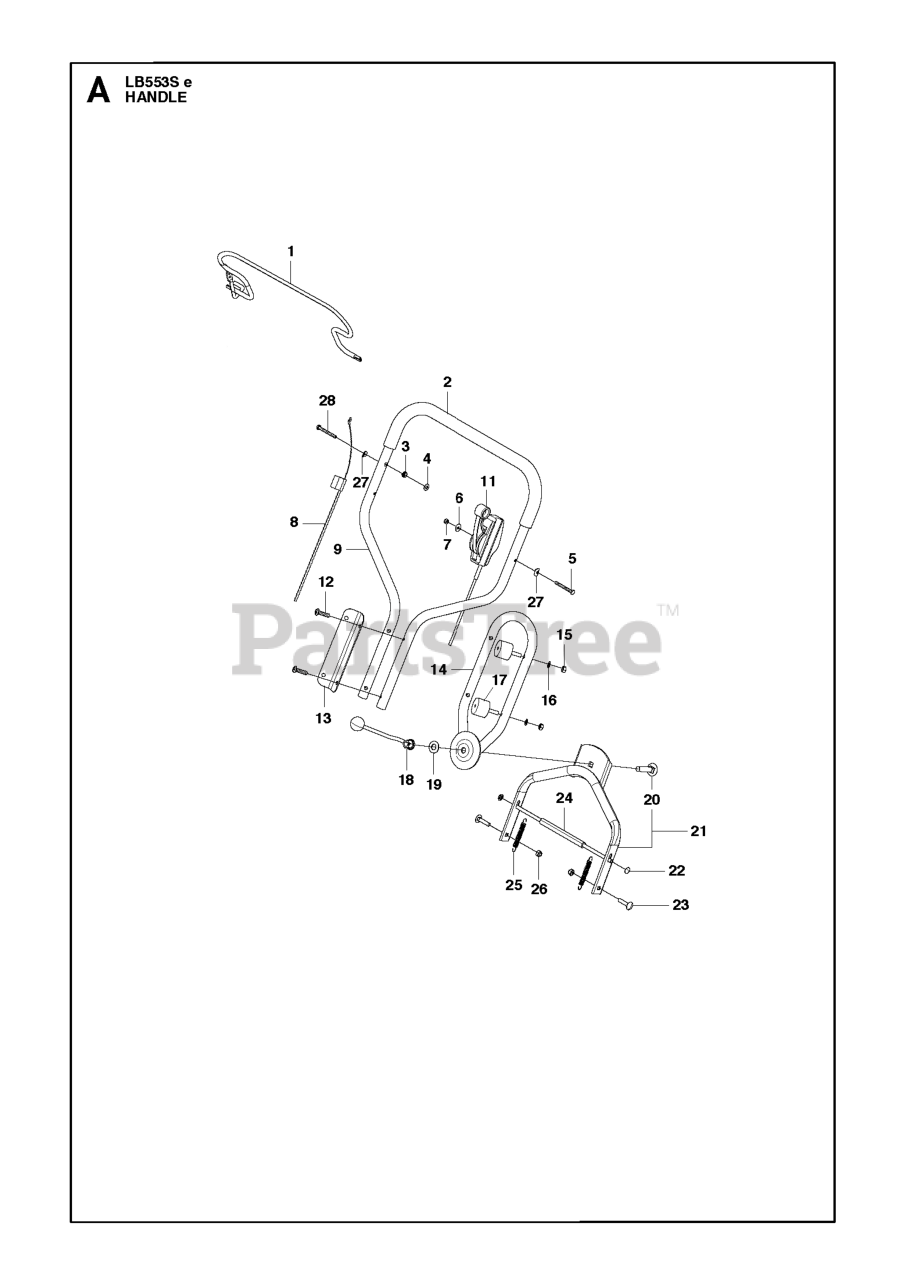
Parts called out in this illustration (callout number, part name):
5	SCREW M6X55
7	NUT FLANGE - M6
15	NUT
22	WASHER STARLOCK WITH CAP
23	RETAINING RING SGA 10
26	LOCKNUT M8
28	SCREW
